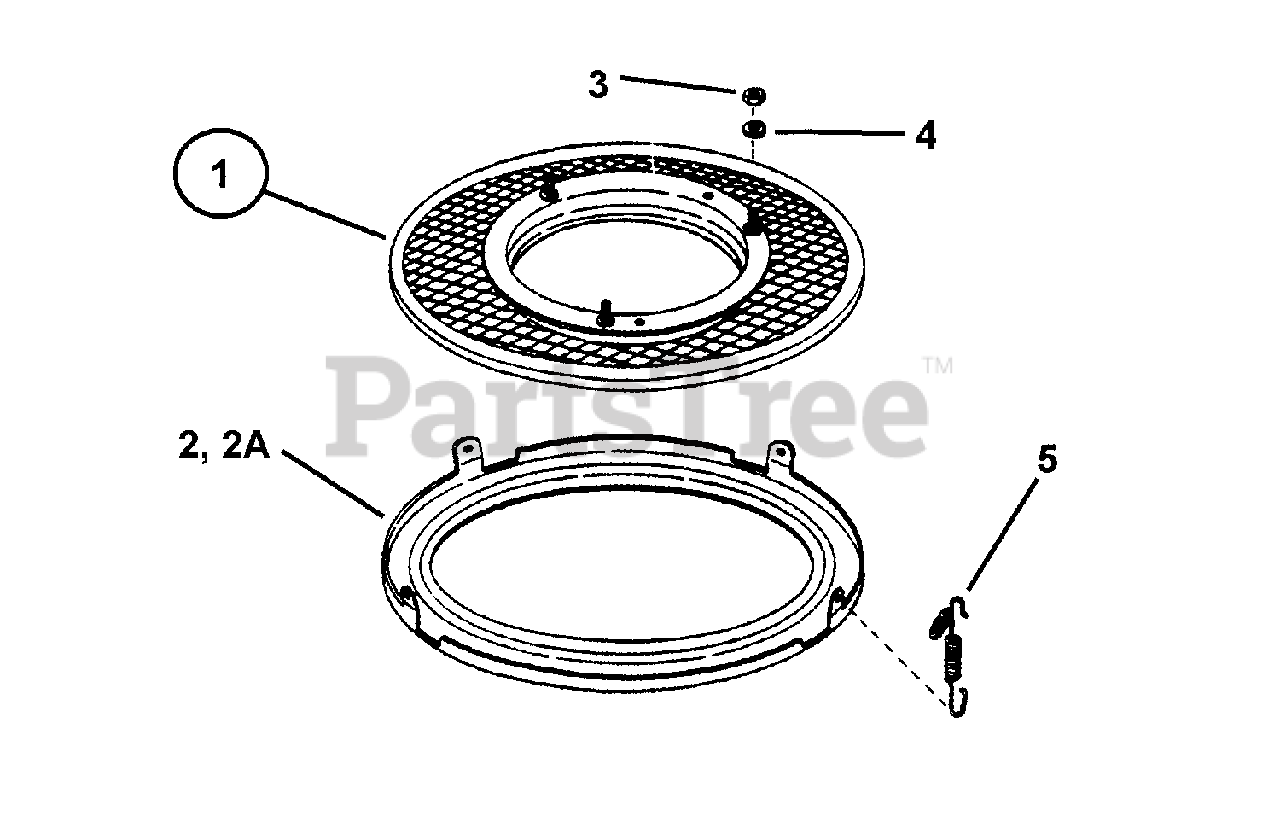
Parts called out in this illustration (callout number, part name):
1	SCREEN, Fastener Assembly
2	RING, Bottom (21.77" Inside Diameter)
2A	RING, Bottom (22.60" Inside Diameter)
3	NUT, 5/16-24 Hex, GR5
4	WASHER, 5/16" Split Lock
5	SPRING
